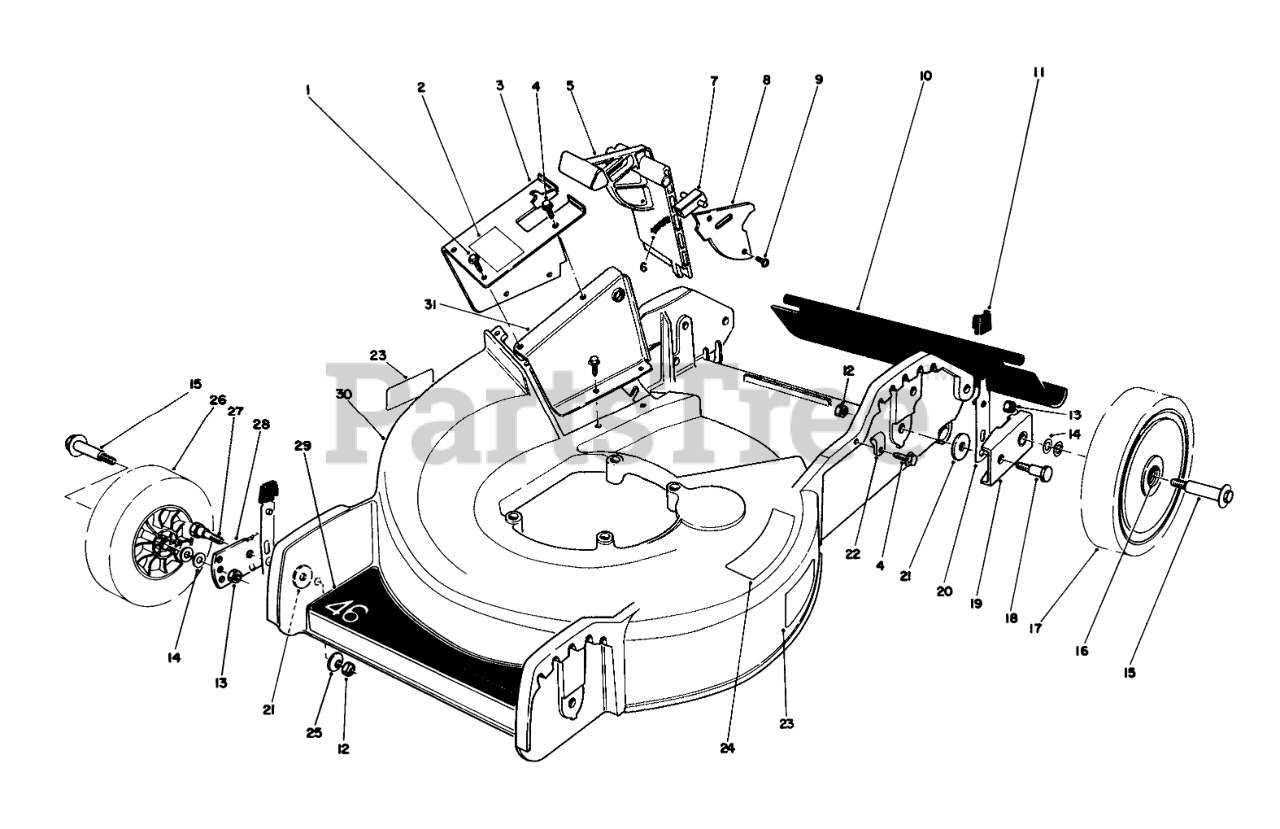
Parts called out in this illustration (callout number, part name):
1	SCREW
2	DECAL - DANGER
3	Tunnel-Outer (Incl. Ref. #2)
4	SCREW
5	Door-Mulching
6	SPRING-COMPRESSION, LATCH
7	Door Latch
8	Cover-Door
10	SHIELD - TRAILING
11	KNOB-ARM
12	NUT-LOCK, NI
13	Nut
14	WASHER
15	BOLT-WHEEL
16	BUSHING
17	Wheel & Tire Assembly (Incl. Ref. #16)
18	PIVOT SCREW
19	PIVOT ARM ASM
20	SPRING ARM ASM
21	PIVOT WASHER
22	CLAMP-CABLE
23	Decal Danger
24	DECAL - STEP PAD INT'L
25	WASHER-BELLEVILLE
26	Wheel & Tire Assembly (Inc. Ref. #16)
27	5/16-18 PIVOT SCREW
28	PIVOT ARM ASSY
29	Decal-Deck
30	Housing (Incl. Ref. #23)
31	Tunnel-Inner
